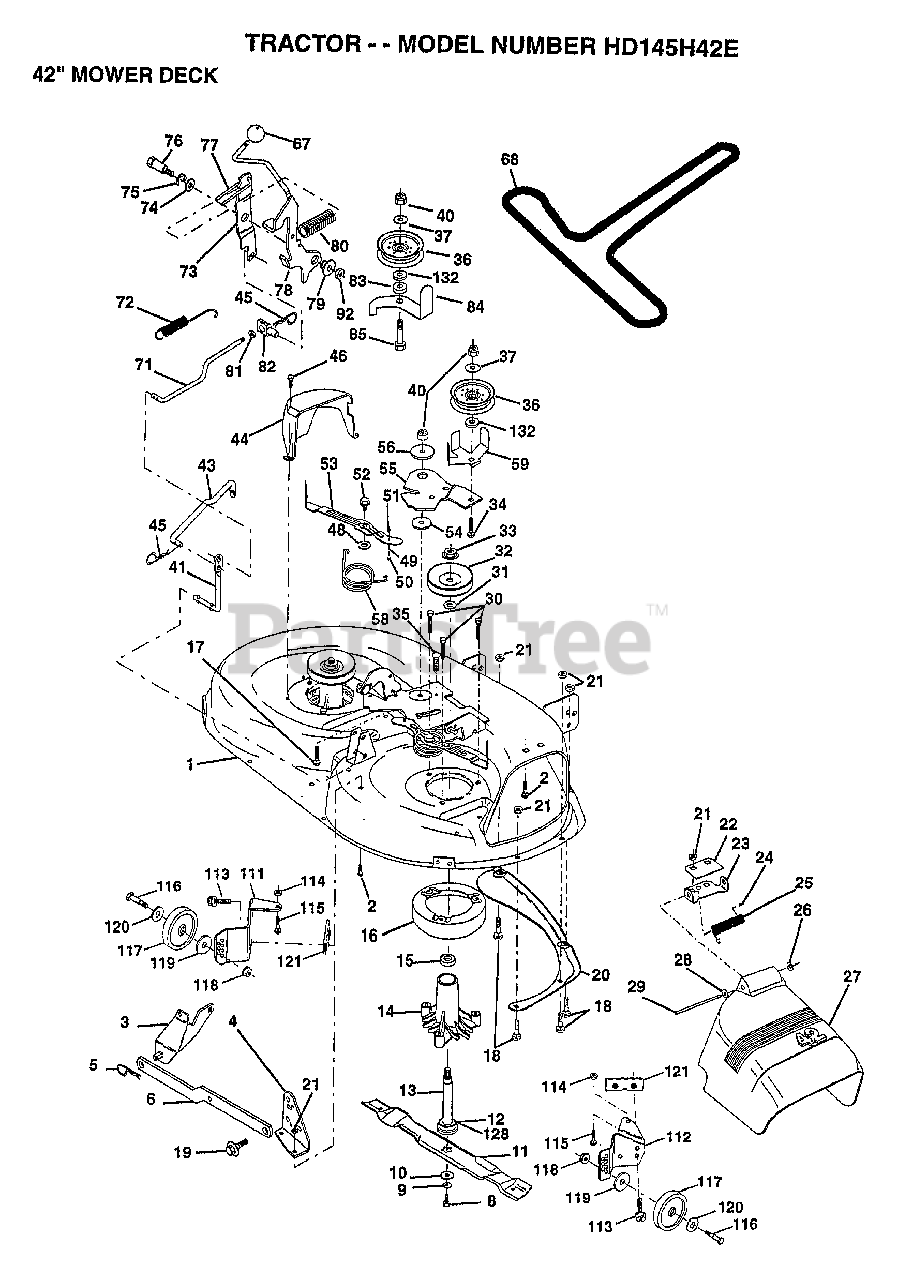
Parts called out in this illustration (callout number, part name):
1	DECK.WELD.42.
2	BOLT
3	BRKT ASM SWAY BAR
4	BRKT DECK SW BAR
8	BLADE BOLT
10	WASHER.HARD.BLADE
11	"BLADE.42"" HIPERF"
12	BEARING.BALL
14	HSG ASM MANDREL
15	BEARING
16	STRIPPER RND MWR
17	BOLT RDHD 3/8-16
18	BOLT
19	BOLT SHD 5/16-18
22	STIFFENER BRKT
23	DEFLECTOR BRKT
24	CAP-SLEEVE LT
25	SPRING TORSION
26	NUT PUSH M
27	DEFLECTOR.SHIELD
28	WASHER
29	HINGE ROD
31	WASHER
32	PULLEY.MANDREL.42
34	BOLT
35	XMAS TREE FASTNER
36	FLAT IDLER PULLEY
37	WASHER
41	PIVOT ROD
43	ROD CLUTCH W/NIBS
44	GUARD MAND LH BLK
45	RETAINER M
46	SCREW.1/4-20X5/8
48	HARD SMALL WASHER
49	ROLLER ASM-CAM
50	SHOULDER BOLT
51	LOCKNUT
52	BOLT.SHLD.5/16-18
54	HARDENED WASHER
55	ARM-IDLER
56	SPACER RETAINER
58	SPRING TORSN BRAK
59	GUARD IDLER TUV
67	KNOB T(3/8 HOLE)
68	BELT.V.T-PATH
71	ROD CLUTCH 38/42
72	RETURN SPRING
73	CLUTCH ARM SECOND
74	WASHER
75	RING
76	SHOULDER BOLT
77	SPRING KEEPER
78	LEVER ASM-CLUTCH
79	BUSHING
80	SPRING.CLUTCH.MWR
81	NUT
82	TRUNION ADJ
83	WASHER
84	"KEEPER-BELT,FIXED"
85	BOLT RDHD 3/8-16
92	NUT
111	BRACKET.GWHL.LH.
112	BRACKET.GWHL.RH.
113	SCREW
116	BOLT M
117	WHEEL.GAGE.BLK.PL
118	LOCKNUT
119	WASHER
120	WASHER
121	BRACKET.EXTRD.GWL
128	WASHER.FELT.
132	WASHER GT
